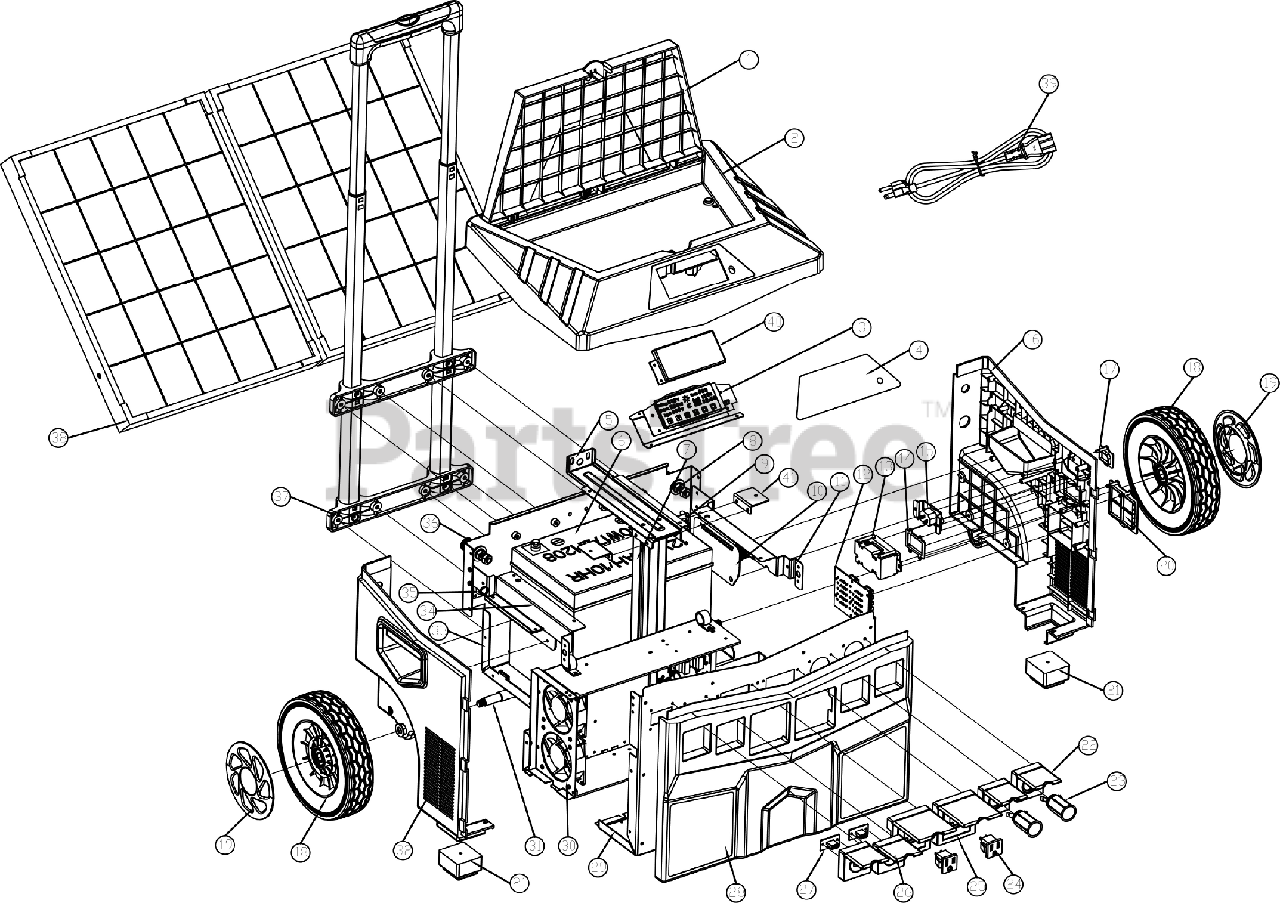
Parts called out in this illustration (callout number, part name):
1	STORAGE CAP
2	UPPER COVER
4	FILM LABEL
5	BATTERY FIXING BAR
6	100AH BATTERY
7	BATTERY FIXING STAND
8	JUMPSTART TERMINAL-POSITIVE
9	MC4 SOLAR TERMINAL-MALE
10	CARRIER BRACKET
11	RIGHT CONNECTING BAR
14	GFCI COVER
15	AC CHARGER SOCKET
16	RIGHT HOUSING
17	SOCKET CAP
19	WHEEL COVER
20	FUSE COMPARTMENT CAP
21	RUBBER FOOT
22	LIGHTER SOCKET FRAME
23	LIGHTER SOCKET
24	AC SOCKET
25	AC SOCKET FRAME
26	USB PORT FRAME
28	FRONT PLASTIC HOUSING
29	FRONT METAL HOUSING
31	WHEEL SHAFT
32	LEFT HOUSING
33	REAR METAL HOUSING
34	LEFT CONNECTING BAR
35	MC4 SOLAR TERMINAL-FEMALE
36	JUMPSTART TERMINAL-NEGATIVE
37	TELESCOPE HANDLE
38	ACCESSORY, EGEN, 60W SOLAR PANEL
38	ACCESSORY, EGEN, 150W SOLAR PANEL
38	ACCESSORY, EGEN, 25FT, PAIR, MC4 CABLE
39	POWER CORD
40	LCD COVER
41	UPPER COVER BRACKET
